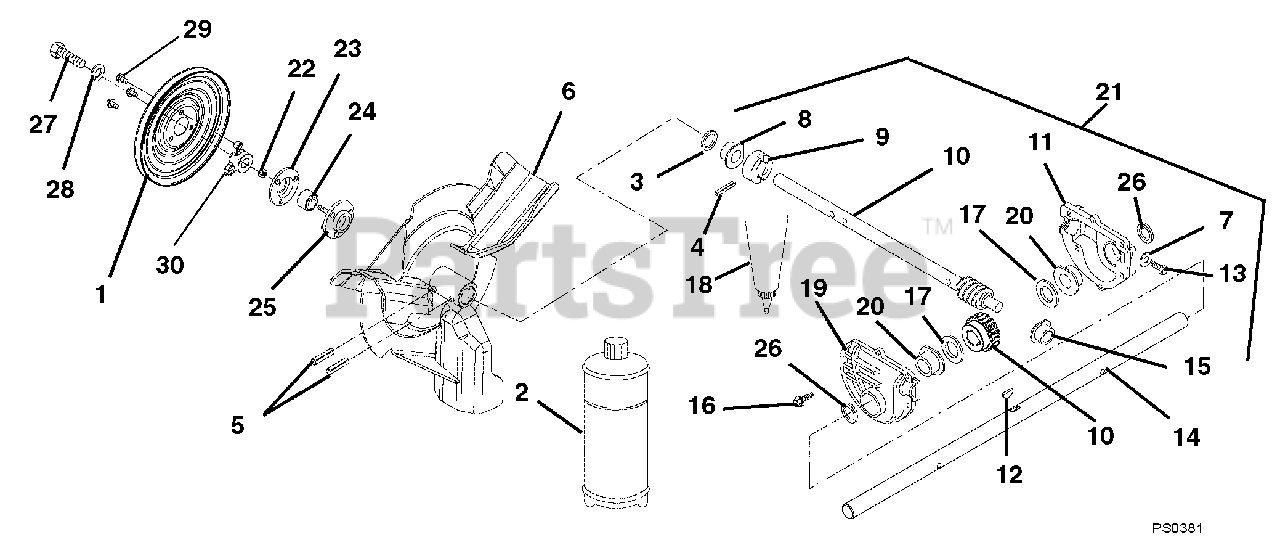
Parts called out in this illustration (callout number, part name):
1	PULLEY,SPIN FORM SINGLE GROOVE
2	ARIENS 16 OZ.BOTTLE OF L2 LUBE
3	SEAL-OIL.748X1.375X.247 GRD OD
4	@PIN-GRV .188X1.25 TP E ALLOY
5	PIN-ROLL .250X1.75
6	IMPELLER, COMPACT 12" 3-BLADE
7	WSHR-FIBER .437X.656X.032
8	BSHG-FLG .750X1.000X.750X1.250
9	THRUST COLLAR, .75" ID
10	SHAFT AND WORM GEAR ASSEMBLY
11	GEARCASE CASTING, MACHINED LH
12	KEY-WDRF .19X.63 HRD #61
13	SCR-TAP .38-16X.75 ROLOK YZ WX
14	SHAFT, RAKE - 22" (.750 DIA)
15	BSHG-FLG .502X1X.750
16	@SCR-TAP .25-20X1.00 HWH TR YZ
17	WSHR-FL-STL.755X1.375X.062YWZC
18	LOCTITE 518 GASKET--6ML TUBE
19	GEARCASE CASTING, MACHINED RH
20	BSHG-FLG .753X1.127X.500X1.501
21	GEAR CASE ASSEMBLY - 22" ALUM.
22	@NUT-LK-CTR .25-20 YWZC
23	BEARING FLANGE
24	BRG-BALL .750X1.750X.50
25	BEARING FLANGE
26	SEAL-OIL .750X1.375X.25
27	BLT-HEX .31-24X.75 YWZC GR5
28	WSHR-LK .312X.097 HVY YWZC
29	@SCR-TAP .31-18X.50 HWH TR YWZ
30	PULLEY HUB, BOLT-ON D-BORE .75
